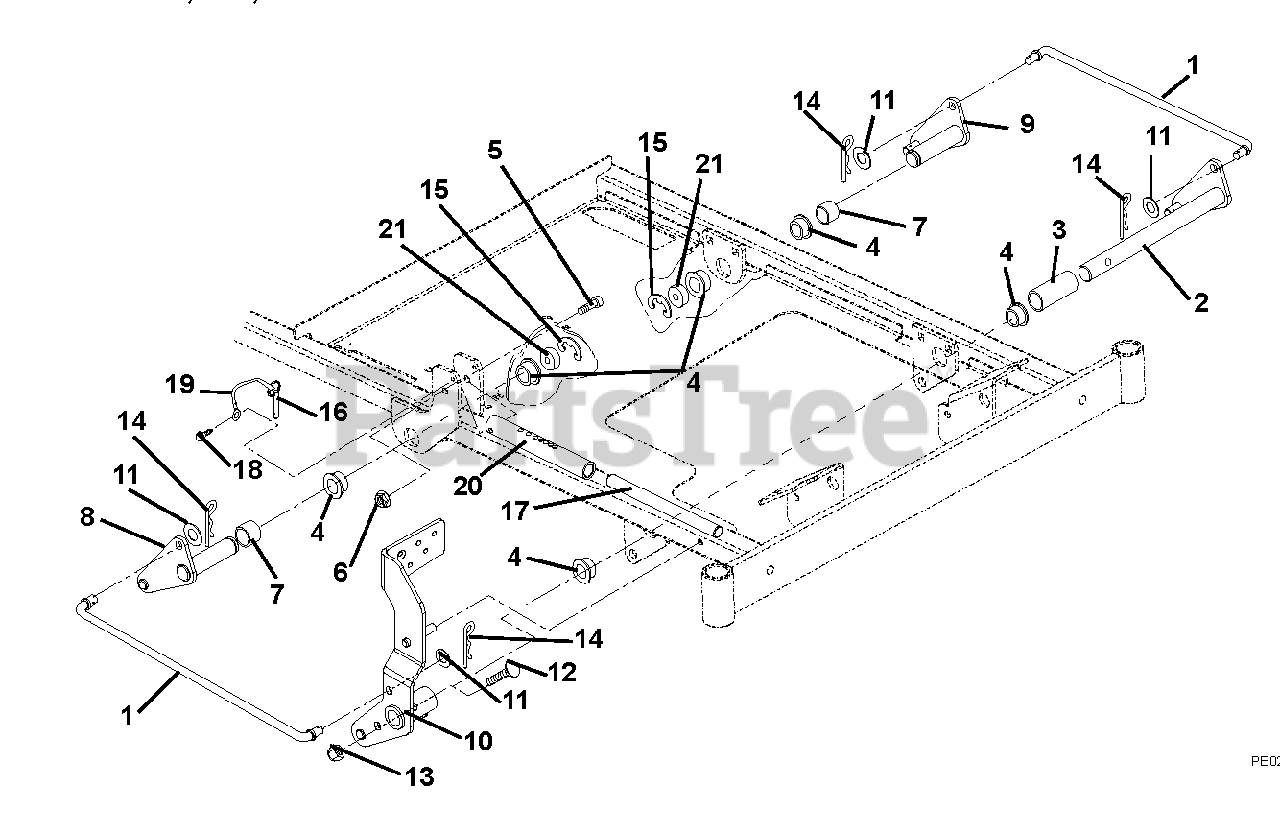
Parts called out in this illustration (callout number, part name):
1	Rod, Lift
2	Weldment, Front Lift
3	Bushing, Front
4	Bushing-Flange 1.00 x 1.12 x .62 x 1.50 Bronze
5	Bolt, Hex .38-16 x 2.75
6	Nut, .38-16 Flange Nyloc
7	Bushing, Rear
8	Weldment, Lift, Rear Right Hand
9	Weldment, Lift, Rear Left Hand
10	Weldment, Foot Pedal
11	Washer-Flat-Steel .531 x 1.06 x .095
12	Bolt, Hex .38-16 x 2.00 Grade 5
13	Nut .38-16 Flange Nyloc
14	Pin, Hair External
15	Ring, Retaining .82 x 1.50 x .05
16	Pin, Spring Ball .375 O.D. x 1.50
17	Rod, Lift
18	Screw-Tapping .250-20 x .37 Hex Washer Head
19	Hood Cable
20	Tube, Lift Stop
21	Spacer, Rear Lift
